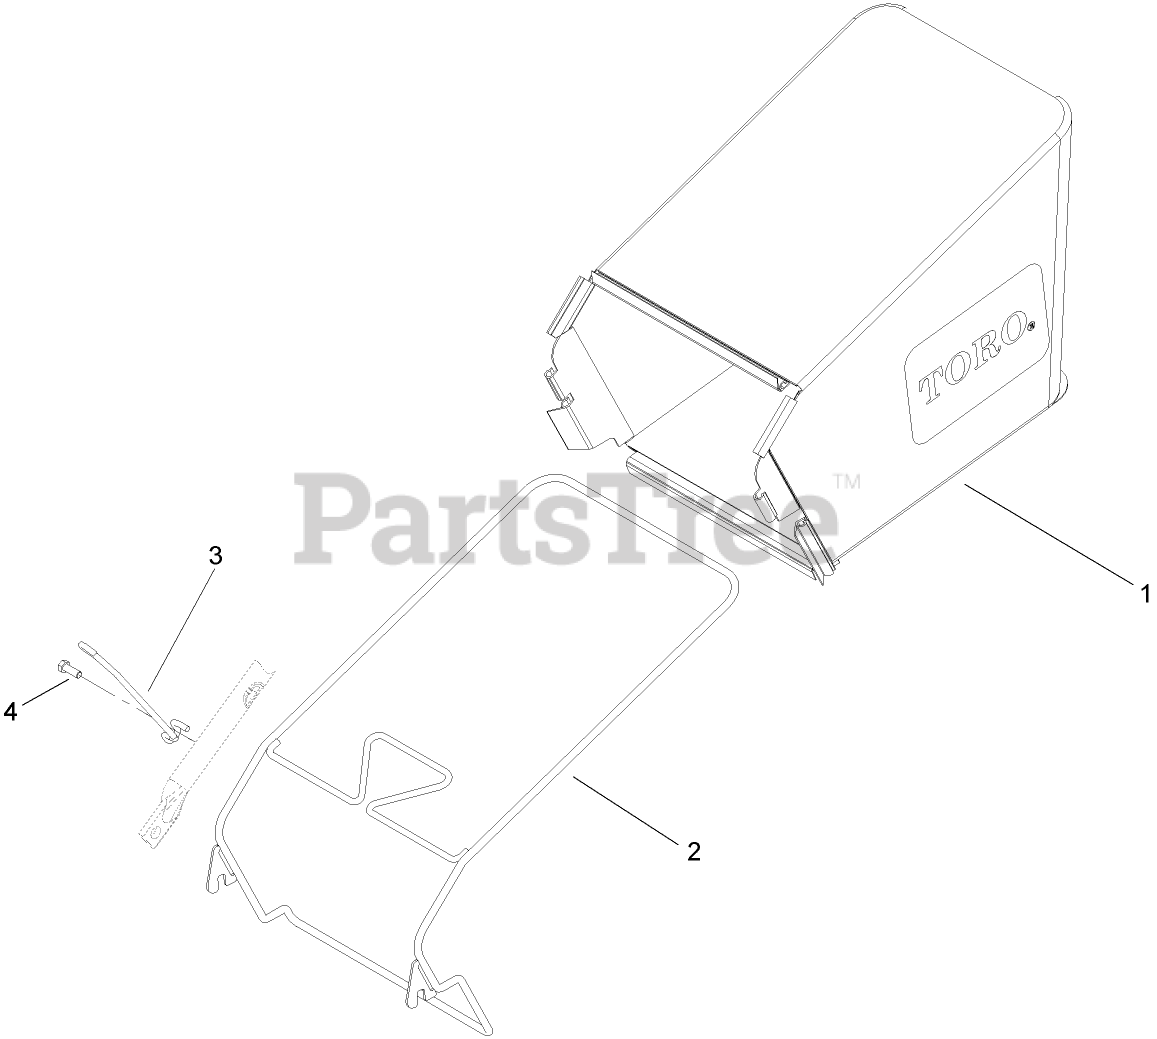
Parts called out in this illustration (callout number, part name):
1	GRASS BAG ASM
2	BAG FRAME ASM
3	HOOK-ROPE, DISPLACEMENT
4	SCREW-SHWH, THREAD FORMING
